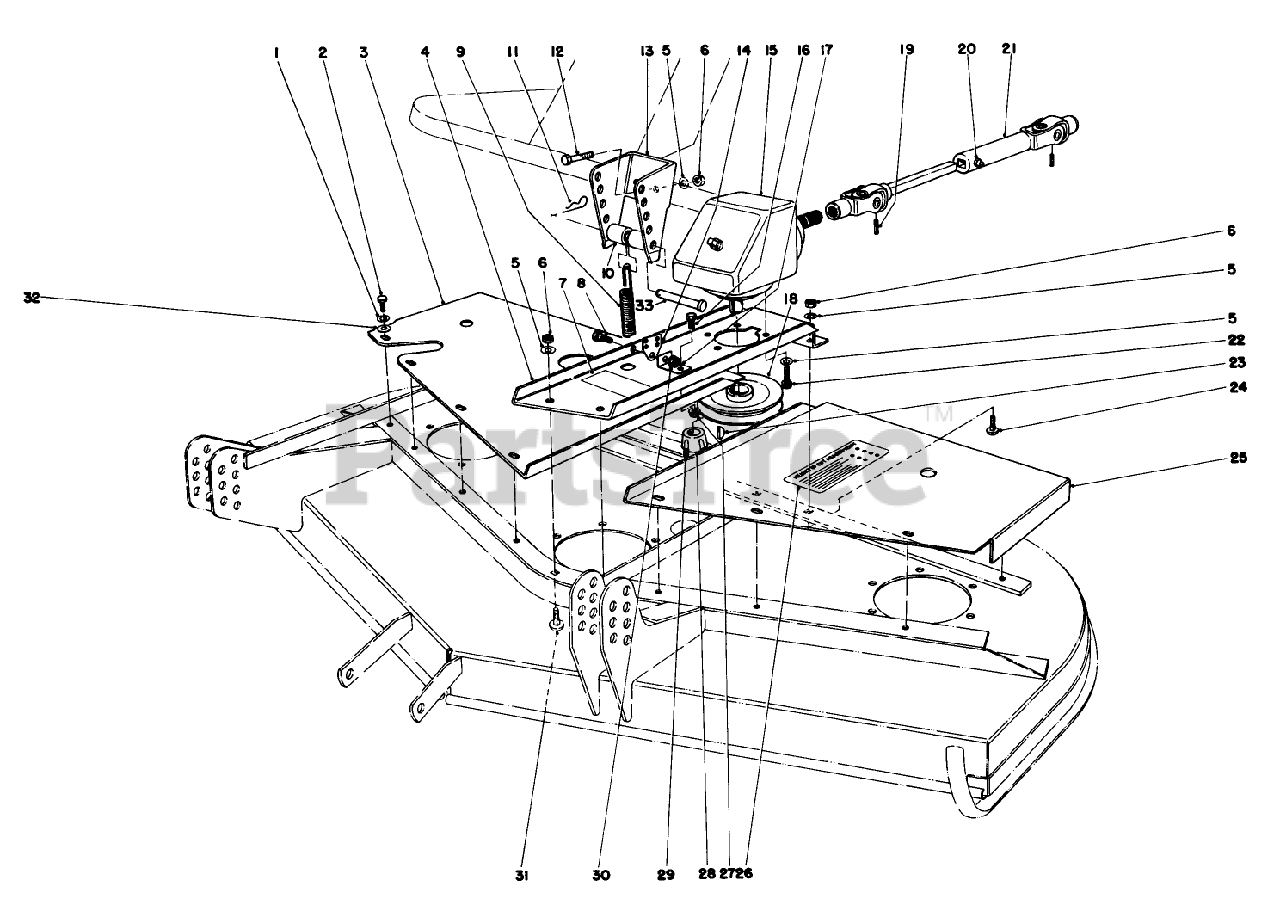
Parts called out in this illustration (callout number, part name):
1	WASHER-LOCK
2	SCREW THD 1/4 20 5/8
3	RH COVER WA R
4	Base-Bear Box
5	WASHER-LOCK
6	NUT-HEX
7	Decal-Caution
8	BOLT-SHOULDER
9	Spring-Extension
10	SPACER
11	PIN-HAIR
12	SCREW-HH
13	SPRING BRACKET R
14	SPRING END R
15	GEAR BOX ASM
16	SCREW-HH
17	EXTENSION BRKT R
18	PULLEY WA BO
19	PIN-ROLL
20	FITTING-GREASE
21	UNIVERSAL JOINT
22	SCREW-HSH
23	KEY-WOODRUFF
24	BOLT-CARR
25	LH COVER WA R
26	DECAL
27	NUT-HF
28	BUSHING-LOCK, TAPER
29	SCREW-SET, HSH
30	NUT-HHF, WHIZ
31	SCREW-CARR
32	WASHER-FLAT
33	PIN-CLEVIS
